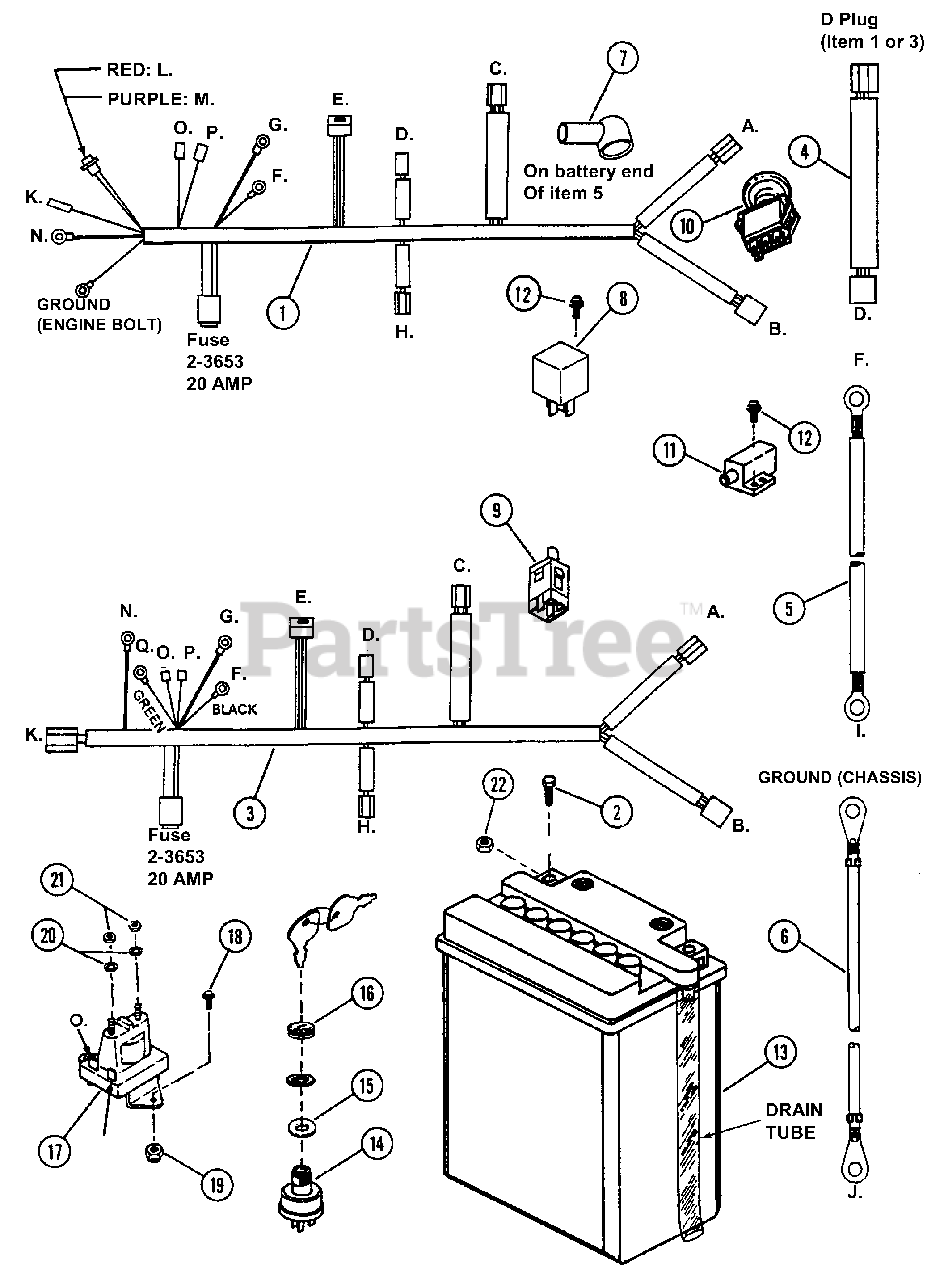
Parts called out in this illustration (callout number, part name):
1	WIRING HARNESS (Briggs 14HP)
2	SCREW, #10-24 x 1/2" Hex Head Cap
3	WIRING HARNESS (Kohler 15HP)
4	WIRING HARNESS, Warner Clutch
5	WIRE, Positive, 13"
6	WIRE, Negative, 14"
7	COVER, Battery Cable
8	RELAY, Operator Presence Control
9	SWITCH, Seat (DP, NO/NC SNAP-IN)
10	SWITCH, PTO Electric Clutch
11	SWITCH, Park Break
12	SCREW, #10-24 x 1/2" Hex Washer Self-Tap (Torx)
13	BATTERY, 12 Volt, 14 Amp, 190 Cold Cranking Amp
14	SWITCH, Ignition (After-fire Solenoid)
16	BEZEL
17	SOLENOID, 12 Volt
18	SCREW, 1/4-20 x 1/2" Hex Head Cap, Grade 5
19	NUT, 1/4-20 Hex Flange Lock, Grade 5
20	WASHER, 1/4 Internal Tooth Lock
21	NUT, 1/4-20 Hex Jam
22	NUT, #10-24 Hex Twin "Whiz" Lock
